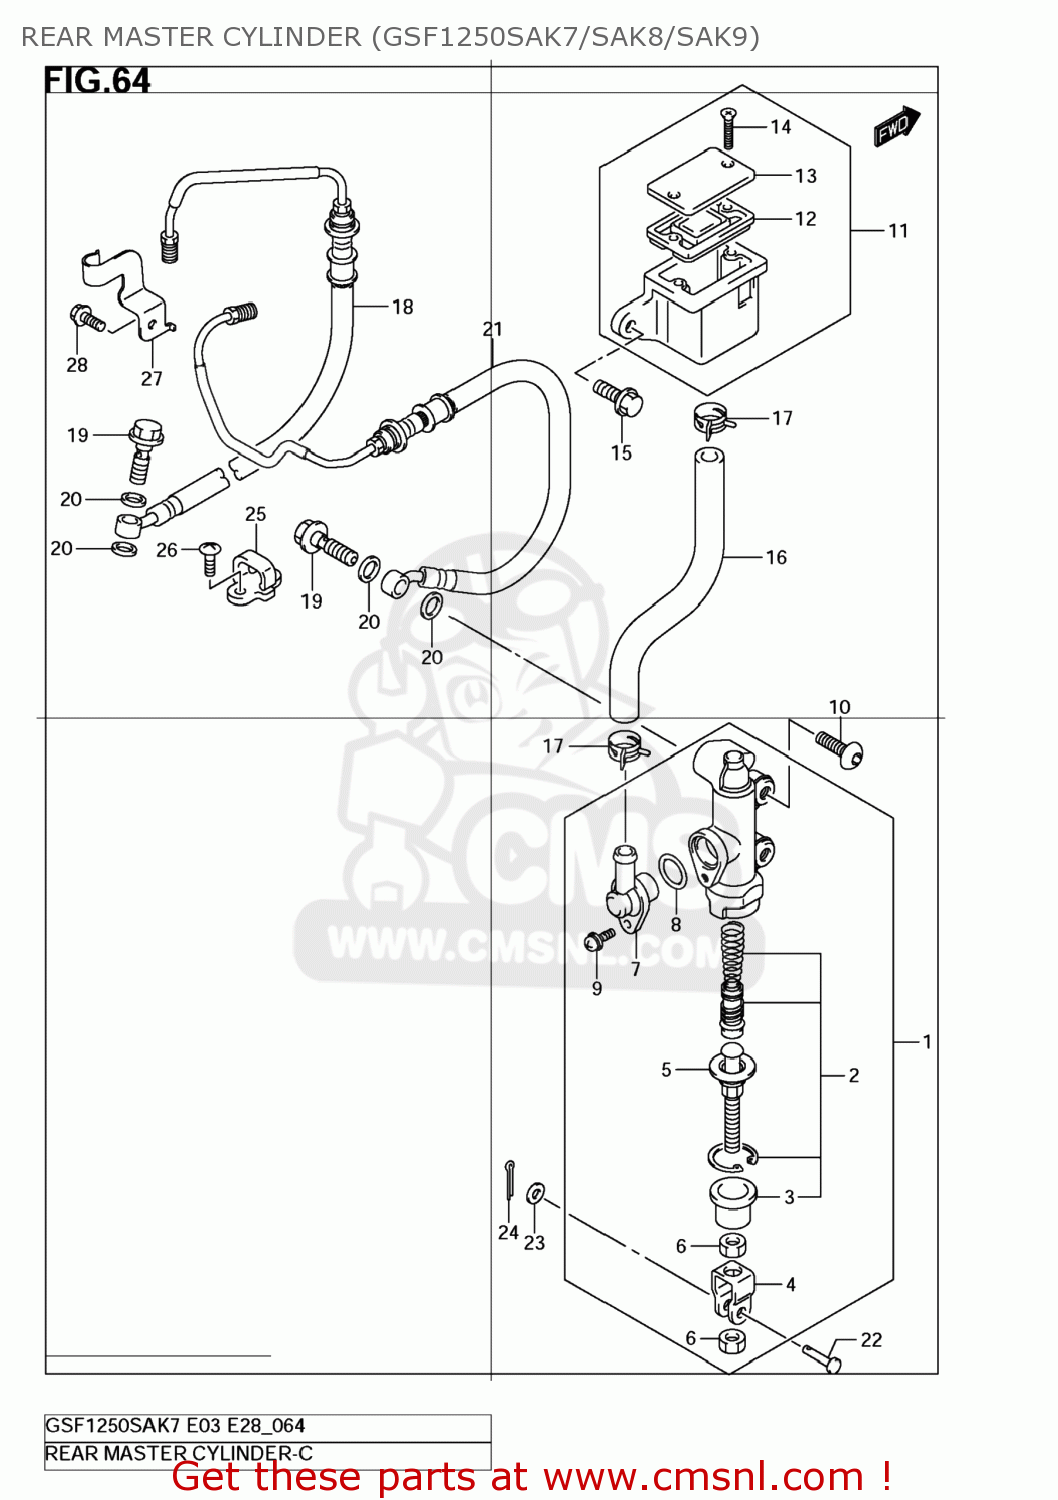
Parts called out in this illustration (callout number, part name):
1	CYLINDER ASSY,RR MASTER
2	PISTON/CUP SET
3	BOOT
4	YOKE
5	ROD,PUSH
6	NUT
7	CONNECTOR
8	O RING
9	SCREW
10	BOLT(8X20)
11	TANK ASSY,RESERVOIR
12	DIAPHRAGM
13	CAP
14	SCREW
15	BOLT
16	HOSE,RR RESERVOIR TANK
17	CLIP
18	HOSE ASSY,RR BRAKE NO.1
19	BOLT UNION
20	WASHER(10X15X1.5)
21	HOSE ASSY,RR BRAKE NO.2
22	PIN(6X18.2)
23	WASHER
24	PIN
25	GUIDE,RR BRAKE HOSE
26	SCREW
27	CLAMP,RR BRAKE HOSE NO.2
28	BOLT
